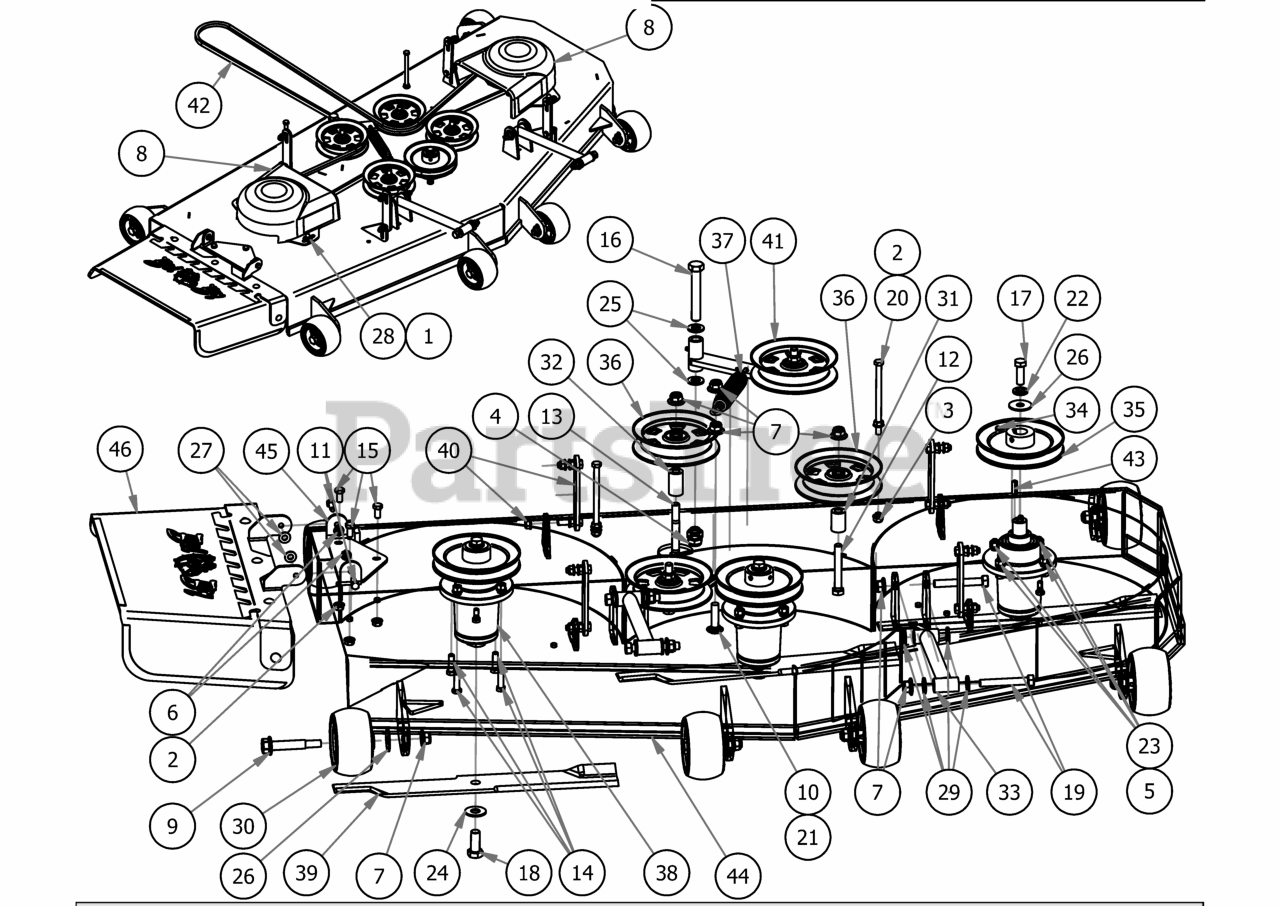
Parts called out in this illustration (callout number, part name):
1	Acorn nut-pulley Cover
2	3/8" Flange Nut
3	3/8" Nylock Flange Nut
4	5/8-11 Nylon Insert Jam Half Nut
5	3/8" Hex Nut
6	5/16" Nylon Flange Nut
7	1/2-13 Nylon Flange Nut
8	Pulley Cover
9	Deck Wheel Bolt
10	1/2 x 2" Carriage Bolt
11	5/16-18 x 1 GR 5 Hex Bolt Zinc
12	1/2 x 3 1/2 Flange Bolt Grade 8
13	1/2" x 4" Bolt (Grade 8)
14	3/8" x 1 1/4" Hex Bolt
15	3/8" x 3/4" Hex Bolt
16	5/8" x 4" Hex Bolt
17	1/2"-20 x 1 1/2 - Grade 5 Fine Thread Bolt
18	5/8 x 1 1/2 Grade 8 Hex Bolt (Fine)
19	1/2-13 x 3 1/2 GR 5 Hex Bolt
20	3/8-16 x 5 1/2 Hex Bolt
21	.517 Square Hole Round Washer
22	1/2" Lock Washer Zinc
23	3/8" Lock Washer
24	5/8'' Flat Washer
25	.630 ID Plastic Washer
26	1/2" Belleville Washer
27	.360 ID Plastic Washer
28	.360 ID Plastic Washer-Black
29	.505 Nylon Spacer
30	Deck Wheel
31	.502 ID X .750 OD X 1.500 Long Spacer
32	1 3/4" Pulley Spacer
33	MZ/ZT Deck Locator
34	5/16 Set Screw
35	6 1/4" Drive Pulley
36	5-3/4 Idler Pulley
37	Deck Idler Spring
38	Spindle Assembly
39	60 Inch Fusion Blade
40	Deck Hanger Assembly
41	2017 MZ/ZT Deck Idler Assembly
43	1/4" x 1" Key
44	60 ZT Welded Deck Shell
45	Discharge Chute Hanger (deck mounted)
46	Discharge Chute Assembly
